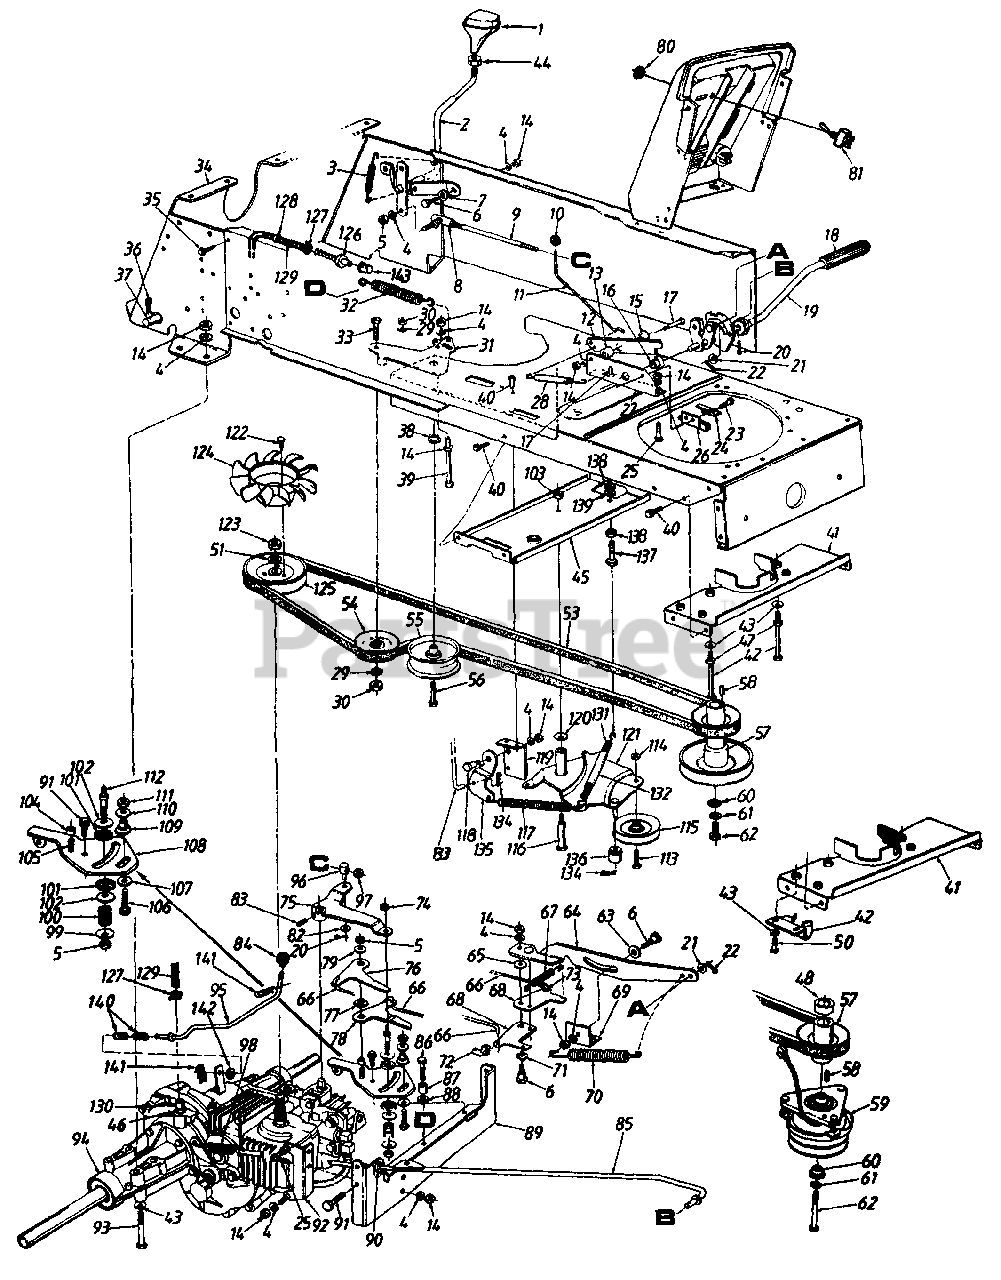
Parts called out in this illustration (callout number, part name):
1	Shift Knob
2	Speed Control Lever Ass'y.
3	Ext. Spring 2.75" Lg.
4	L-Wash. 5/16" I.D.
5	Hex Nut 5/16-24 Thd.
6	Shld. Bolt .437" Dia. x .268"
7	Spr. Wash .445" I.D. x .75" O.D.
8	Ball Joint 5/16-24 Thd.
9	Speed Selector Adjusting Rod
10	Ball Knob
11	Brake Lockout Rod
14	Hex Nut 5/16-18 Thd.
15	Shld. Spacer .27" Lg.
16	Hex Flange Bearing
17	Hex Bolt 5/16-18 x 1.25" Lg.
18	Foot Pad
21	Fl-Wash .34" I.D. x .68" O.D.
22	Cotter Pin 1/8" Dia. x 1" Lg.
23	Hex B-Tap Scr. #10 x .62" Lg.
24	Switch Plate
25	Hex Bolt 5/16-18 x .75" Lg.
26	Safety Switch (Clutch)
27	Clutch Ass'y. Mtg. Brkt.
28	Ext. Spring 2.51" Lg.
29	L-Wash. 3/8" I.D.
30	Hex Nut 3/8-16 Thd.
31	idler Brkt.
32	Ext. Spring 4.75" Lg.
33	Hex Bolt 3/8-16 x 1.5" Lg.
36	Hitch Pin
37	Hitch Rod
38	Shld. Spacer .625" I.D.
39	Hex Bolt 5/16-18 x 2.75" Lg.
40	Hex TT-Tap Scr. 1/4-20 x .5" Lg.
44	Hex Jam Nut 3/8-16 Thd. (Gr. 5)
46	O-Ring
47	Hex Nut 5/16-18 Thd. (Gr. 5)
48	Clutch Spacer
50	Hex Bolt 5/16-18 x .75" Lg. (Gr. 5)
53	"V"-Belt
54	Idler Pulley
55	Fl-Idler Pulley
56	Hex Bolt 3/8-16 x 2" Lg. (Gr. 8)
57	Engine Pulley
58	Sq.-Key 1/4" x 1.5" Lg.
59	Electric Clutch
60	Fl-Wash .44" I.D. x 1.25"
61	L-Wash. 7/16" I.D.
62	Hex Bolt 7/16-20 x 1.5" Lg.
63	Fl-Wash .531" I.D. x 1.25" O.D.
64	Neutral Return Link Ass'y.
65	Fl-Wash .344" I.D. x 1.12" O.D. (Hdn.)
66	Connecting Rod
67	Ext. Spring 2.5" Lg.
68	Balancer Brkt.
69	Bracket
70	Ext. Spring 3.94" Lg.
71	Spr.-Wash .445" I.D. x .75" O.D.
72	Rod End Clevis Clip - R.H.
73	Rod End Clevis Clip - L.H.
74	Hex Ins. L-Nut 3/8-24 Thd.
75	Pintle Bracket Ass'y.
76	Flat Scissors
77	Spr. Wash .625" I.D. x .885" O.D.
78	Offset Scissors
79	Fl-Wash .344" I.D. x 1" O.D. (Hdn.)
80	Hex Nut 1/2-27 Thd.
81	Toggle Switch f f
82	Fl-Wash .406" I.D. x .75" O.D.
83	Hex Socket Set Screw
84	Ball Knob
85	Brake Rod
86	Hex Wash. Hd. Scr. 1/4-20 x 1.5"
87	Spacer .39" Lg.
88	Hex Nut 1/4-20 Thd. (Gr. 5)
91	Hex TT-Tap Scr. 5/16-18 x .62"
94	Transaxle
95	Bypass Rod
96	Ferrule 3/8-24 Thd.
97	Hex Jam Nut 3/8-24 Thd.
98	Ext. Spring 4.01" Lg.
99	Fl-Wash .312" I.D. x .75" O.D.
100	Comp. Spring 1.19" Lg.
101	Friction Washer
102	Bell-Wash .40" I.D. x 1.13" O.D.
103	Hex Cent. L-Nut 3/8-16 Thd.
104	Spacer
105	Rib Neck Bolt 5/16-18 x .62" Lg.
106	Hex Bolt 1/4-28 x 1" Lg. (Gr. 5)
107	Fl-Wash .26" I.D. x .72" O.D.
108	Scissors Mtg. Brkt.
109	Centering Gauge Spacer
110	Bell-Wash. 1/4" I.D.
111	Hex Nut 1/4-28 Thd.
112	Friction Disc Stud
113	Hex Bolt 3/8-24 x 1.5" Lg.
114	Hex Cent. L-Nut 3/8-24 Thd.
115	V-Belt Idler
116	Shld. Bolt .498" Dia. x 2.05
117	Ext. Spring 6.12" Lg.
118	Shld. Bolt .437" Dia. x .162"
119	Parking Brake Mtg. Brkt.
120	Bell-Wash .38" I,D. x .88" O.D.
121	Idler Brkt. Deck Ass'y.
122	Hex Tap Scr. #12 x 3/8" Lg.
123	Hex Jam Nut 9/16-18 Thd.
124	Fan
125	Input Pulley
126	Plastic Vent
127	Hose Clamp
128	Cable Tie
129	Hose 1/2" I.D. x 18" Lg.
130	Hose Fltting
131	Ext. Spring 6.37" Lg.
132	Convoluted Conduit
133	Deck Control Rod
134	Internal Cotter Pin
135	Deck Control Pivot Brkt.
136	Spacer
137	Hex Bolt 1/4-20 x 2" Lg.
138	Hex Nut 1/4-20 Thd.
139	L-Wash. 1/4" I.D.
140	Comp. Spring 1" Lg.
141	Hairpin Clip
142	Fl-Wash. 1/4" I.D.
143	Plastic Vent Cap
